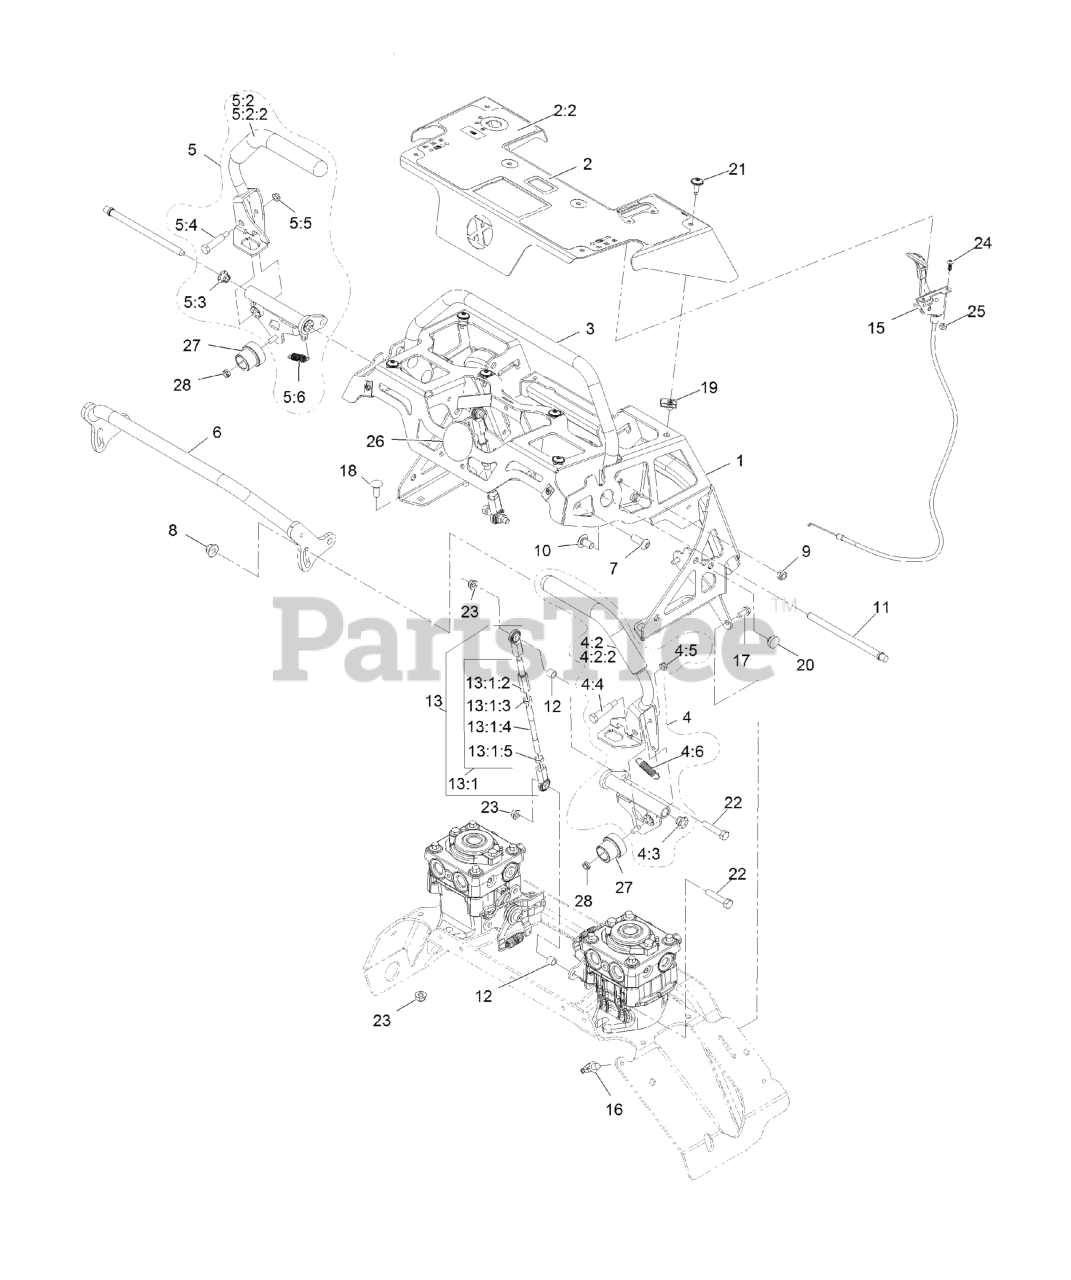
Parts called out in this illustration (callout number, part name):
1	ASM, CONTROL TOWER W/ DECAL
2	ASM, CONTROL PANEL W/ DECAL
2:2	DECAL-CONTROL PANEL EFI
3	WELD, REAR REF BAR
4	ASM, MOTION CONTROL, LT
4:2	ASM, LT CONTROL LEVER W/ GRIP
4:2:2	GRIP, DRIVE LEVER
4:3	BEARING, IGUS
4:4	BOLT-SHOULDER
4:5	NUT-LOCK, NI
4:6	SPRING-EXTENSION
5	ASM, MOTION CONTROL, RT
5:2	ASM, RT CONTROL LEVER W/ GRIP
5:2:2	GRIP, DRIVE LEVER
5:3	BEARING, IGUS
5:4	BOLT-SHOULDER
5:5	NUT-LOCK, NI
5:6	SPRING-EXTENSION
6	WELD, FRONT REF BAR
7	SCREW-HSBH
8	NUT-HF, NI
10	SCREW-CARR
11	PIN, PIVOT
13	ASM, LINKAGE
13:1	ASM, Motion Control Link
13:1:2	ROD-ADJUSTMENT
13:1:3	NUT-HEX JAM, LH
13:1:5	NUT-HJ
15	CABLE, THROTTLE
16	CLIP-TIE
17	SCREW-HWH
18	SCREW-CARR
21	SCREW, TORX
22	SCREW-HH
23	NUT-HF, NI
24	SCREW, BHCS
25	NUT-LOCK, NI
26	DECAL-COVER
28	NUT-LOCK, NI
